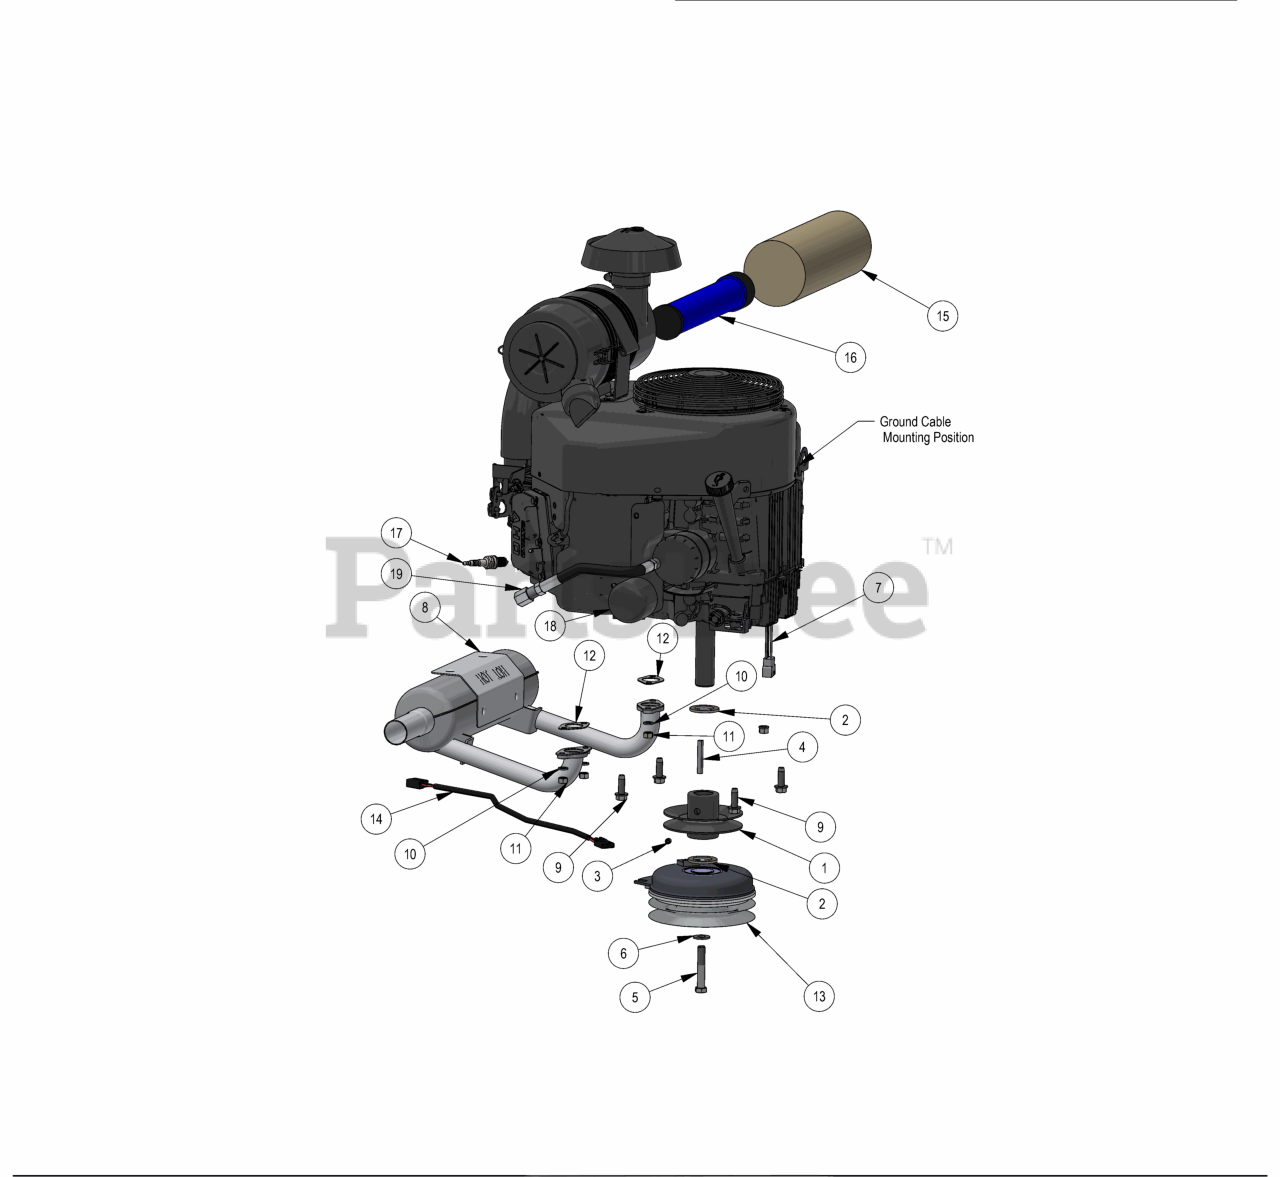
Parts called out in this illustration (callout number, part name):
1	4 3/4 Motor Pulley
2	1.140 ID X 1.750 OD X .132 THICK FLAT WASHER PLAIN
3	5/16-24 X 1/4 SOCKET SET SCREW (CUP PT) PLAIN
4	1/4 X 2 SQ MACHINERY KEY 1018 STL PLAIN
5	7/16-20 X 2-1/2 HEX CAP SCREW (GR.8) ZINC YELLOW
6	3/8 FLAT WASHER USS (1" OD) ZINC
7	2019 Harness Adaptor-Gen2 FX-ALL
8	Exhaust-Stand On-FX691V Kawasaki
9	3/8-16 X 1-1/8 HEX WASHER UNSLOT SERRATED (TRI-LOB) TRS ZINC YELLOW
10	5/16 SPLIT LOCKWASHER ZINC
11	M8-1.25 DIN 934 HEX NUT (CL.8) ZINC
12	Exhaust Gasket
13	Clutch Assembly
14	Clutch Pigtail
15	Canister Air Filter- Outer
16	Canister Air Filter- Inner
17	Spark Plug - Kawasaki
18	Oil Filter
19	Oil drain Hose
20	Engine FX730
